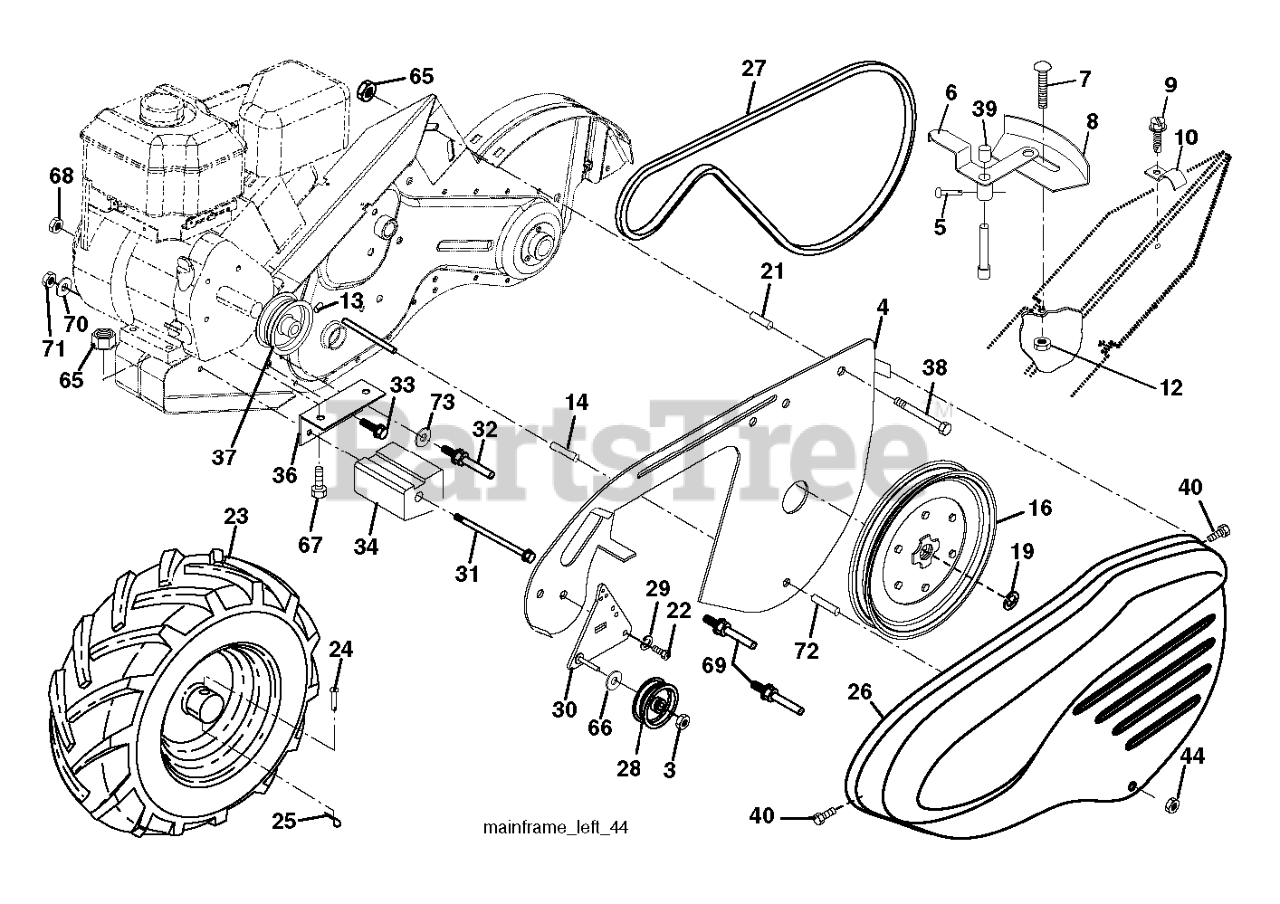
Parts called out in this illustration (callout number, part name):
3	LOCKNUT
4	SHIELD.INNER.BELT.GUARD.RT.BLA
5	PIN.SPIROL.FLARED
6	LEVER.ASM.SHIFT.RED
8	PANEL.INDICATOR.SHIFT.BLACK.
9	TAPPING SCREW
10	CLIP.PLATED
12	NUT
16	SHEAVE, TRANSMISSION
19	RETAINING RING LT
23	WHEEL.ASM.DRT.13X5-6.LT.SILVER
24	RIVET
25	RETAINER M
26	GUARD.BELT.TILLER.ORANGE
27	V-BELT
28	PULLEY-IDLER TI
30	BRACKET.IDLER.ASM.LONG
31	BOLT.FIN.HEX.3/8-16UNC X 11.5
32	SHIFT ARM CRT
33	BOLT
34	COUNTERWEIGHT.LH
36	BRACKET.REINFORCEMENT.LH.PNT
37	PULLEY ENGINE 4L 2.50
38	BOLT
39	CAP.PLUNGER.BLACK
40	SCREW.HEX.WSH.SLT.#10-24X.50
44	NUT.71038.31-18.HEX.NYLOCK
65	LOCKNUT-FLANGE 5/16-18
66	WASHER
67	BOLT
69	KEEPER.BELT.ENGINE
70	WASHER
72	SPACER-SPLIT.327 X .42
73	WASHER
